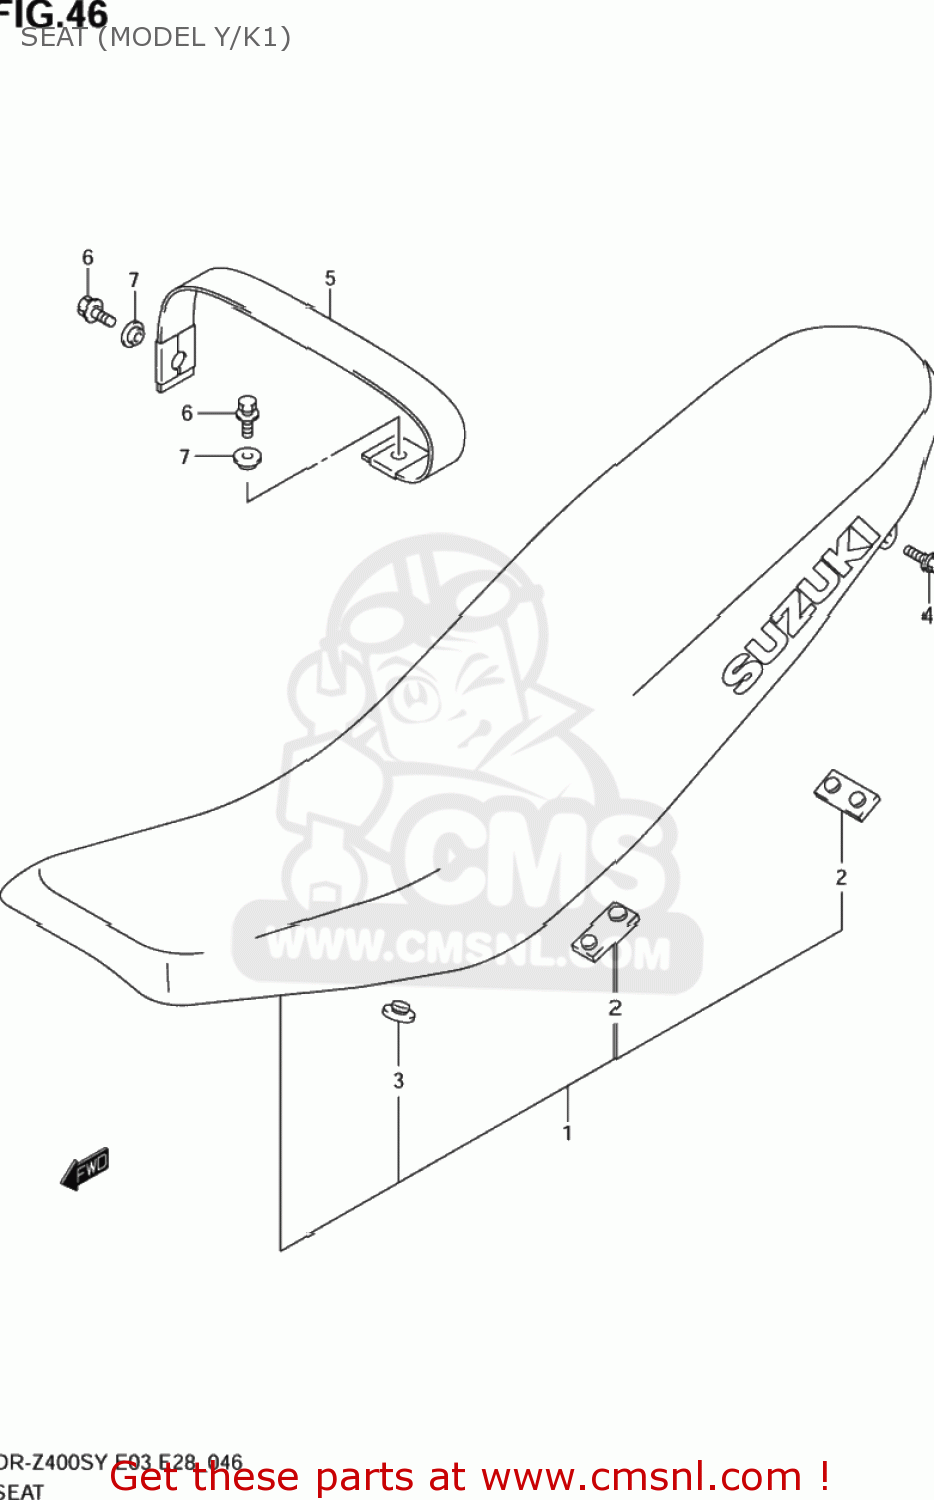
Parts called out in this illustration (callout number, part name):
1	SEAT ASSY
2	CUSHION,SEAT(40X20X6)
3	CUSHION
4	BOLT
5	BAND ASSY,SEAT
6	BOLT(6X25)
7	WASHER
